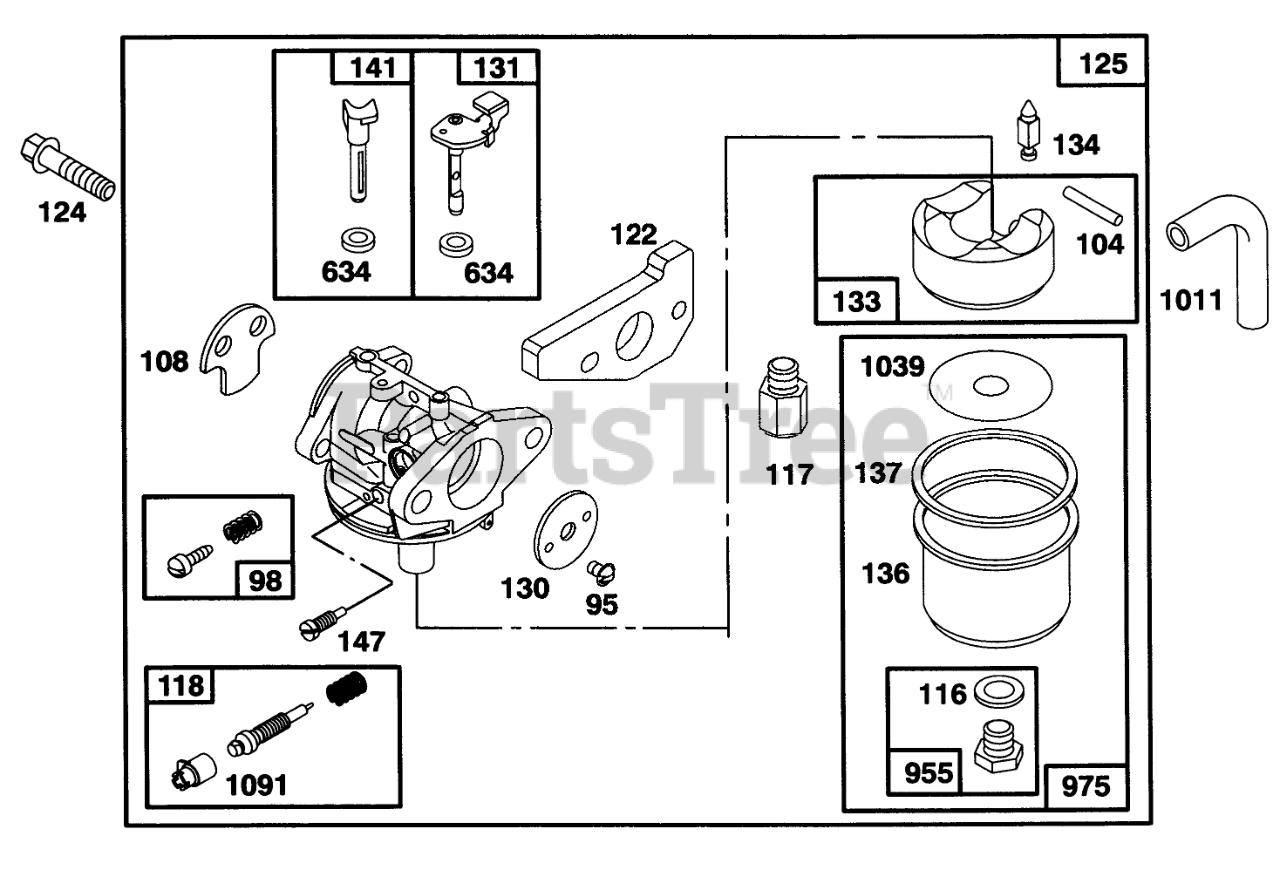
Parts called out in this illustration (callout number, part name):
95	SCREW - ROUND HEAD
98	IDLE ADJUSTING SCREW
104	FLOAT HINGE PIN
108	VALVE - CHOKE
116	SEALING GASKET
117	JET - MAIN
118	VALVE/SPRING - NEEDLE
122	ADAPTER ASSEMBLY
124	HEX HEAD SCREW
125	ASSEMBLY - CARBURETOR
130	THROTTLE VALVE
131	THROTTLE SHAFT
133	FLOAT-CARBURETOR
134	Valve-Inlet (Includes Seat)
136	FLOAT BOWL
137	FLOAT BOWL GASKET
141	CHOKE SHAFT
147	JET - PILOT
634	SEAL WASHER
955	HEX HEAD SCREW
975	CARBURETOR BOWL ASM
1011	VENT TUBE
1039	FLOAT LIMITER
1091	CAP - LIMITER
